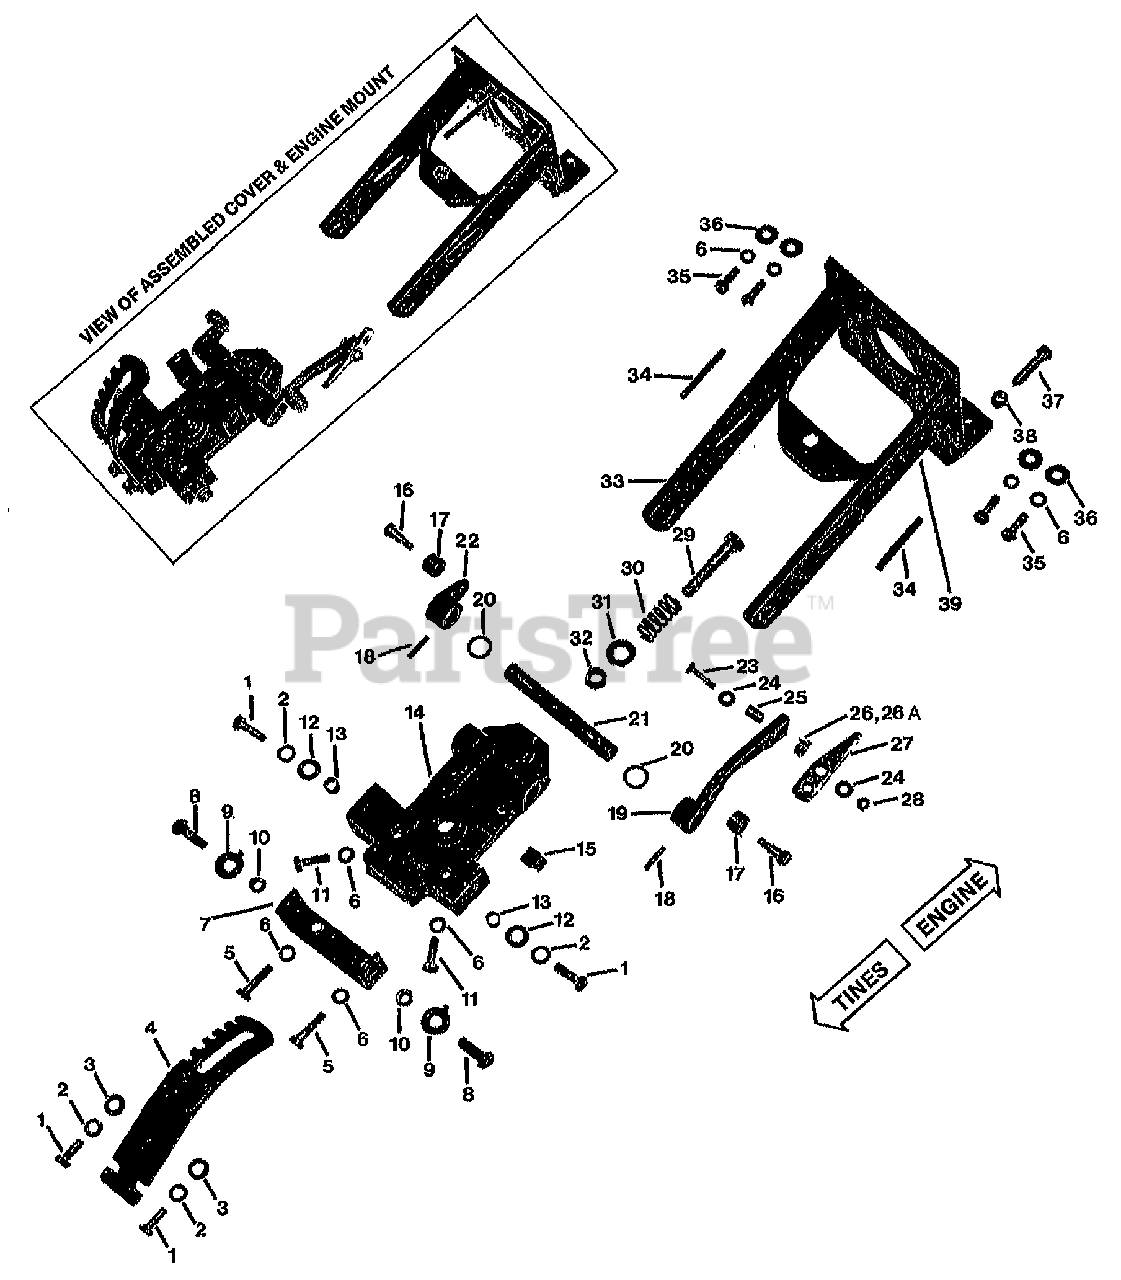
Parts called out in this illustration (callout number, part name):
1	SCR-HH 3/8-16X1.0 G5 ZP
2	WASHER-LK .375 @ DEPL (See Illustration, used in two places.)
3	WASHER-1.0X.438X.104 ZP
4	PLATE-HANDLEBAR ADJUST
5	SCR-HH 5/16-18X1.25 G5ZP (Handlebar attachment bracket to transmission cover.)
6	WASHER-LK .312 ZP (See Illustration, used in three places.)
7	BRKT-HANDLEBAR PIVOT
8	SCR-HH 3/8-16X1.0 G5 ZP (Bracket to handle bars.)
9	WASHER-TAB #
10	NUT-LOCK 3/8-16 NYLON ZP
11	SCR-HH 5/16-18X1.0 G5 ZP (Front cover to tranmission case)
12	WASHER-FLAT 3/8 SAE
13	BUSHING-.5X.375X.375 (Engine mount arms)
14	COVER-TRANS MACH
15	PLUG-PIPE 3/8 NPT (Gear oil fill hole)
16	SCR-SH 5/16-18 X .5 ZP (Eccentric arms to engine mount arms)
17	ROLLER-ECC (Eccentric arms)
18	PIN-ROLL .188 X 1 (Eccentric arms to eccentric shaft)
19	ECC W/SPG & ROLL PIN-RT (Inc. #18 & 26)
20	WASHER # .875 X .65 X .06 (Eccentric shaft)
21	SHAFT-ECC MACH (Eccentric)
22	ECC-LT MACH (Inc. #18)
23	SCR-HH 1/4-20X1.0 ((Eccentric arm to neutral control stop arm)
24	WASHER-FLAT 1/4 SAE
25	BUSHING-.406X.255X.595 (Neutral Control Arm)
26	SPRING-.56 X .4 ZP(Neutral Control Arm FOR S/N 1274 & LATER, DO NOT USE 26A)
26A	SPRING-.56X.4 ZP(FOR S/N 1273 & EARLIER, DO NOT USE 26)
27	ARM-CONTROL ZP (Neutral stop)
28	NUT-LK 1/4-20
29	BOLT-HH 1/2-13 X 2.5 ZP(Reverse adjustment)
30	SPRING-.685X1.75 (Reverse adjustment)
31	WASHER-PLAIN 1/2 ZP
32	NUT-LOCK 1/2-13 NYLON INSERT ZP
33	BRKT-ENG MTG W/DECAL (Inc. 39 & two #34)
34	PIN-SPIROL .25 X 2.5
35	SCR 5/16-24 X 1 (Engine mount to engine)
36	WASHER-.88X312X.08 ZP
37	BOLT-HH 3/8-16X1.5 FTH ZP (Belt adjustment)
38	NUT-HEX 3/8-16 ZP
